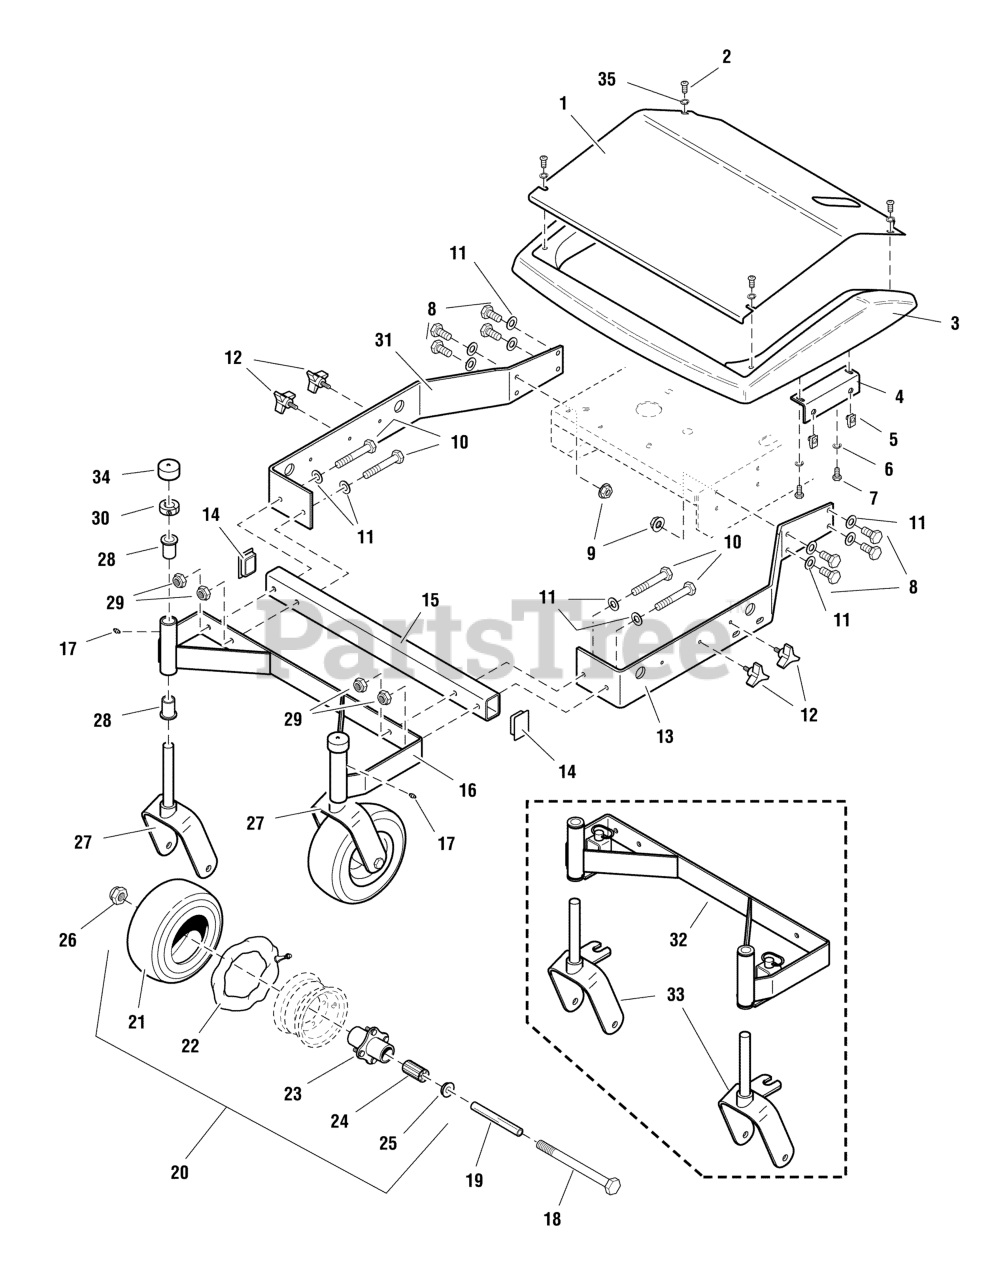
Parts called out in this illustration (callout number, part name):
2	SCREW, Allen Head, 1/4-20 x 1/2
3	GUARD, MOWER HOUSING
4	SHIELD MOUNT BRACKET
5	BODY CLIP, 5/16-18-7GA MATERIAL
6	WASHER, 1/4 LOCK
7	HHCS, 1/4-20 X 0.625, GR5, ZINC/CLEAR
8	BOLT, 3/8-16 X 1" GD5 CZ
9	NUT, 3/8-16 Hex Serrated Flange
10	BOLT, 3/8-16 X 2-1/2" GD5 CZ
11	WASHER, 3/8 SAE
13	FRAME RAIL - LH
14	CAP, Plastic
15	CROSS TUBE
16	ASSM, CASTER MOUNT
17	GREASE FITTING
18	BOLT, 1/2-13 x 5-1/2
19	AXLE, Caster Wheel
20	TIRE ASSM, 9 X 3.5 X 4, SILVER
21	TIRE, Front, 9 x 3.5 x 4
23	HUB & BEARING ASSEMBLY, Complete, Silver
24	BEARING, ROLLER 3/4" ID X 3.25" (ONE PER TIRE)(SV)
25	RETAINER, Bearing
26	NUT, 1/2-13 HEX NYLON LOCK
27	CASTER YOKE
28	BUSHING, Flange
29	NUT, 3/8-16 Hex Nylon Flange
30	COLLAR, 3/4" Split
31	FRAME RAIL - RH
32	CASTER MOUNT FRAME W/ LOCKS, Complete
33	CASTER YOKE
34	CAP,VINYL, 1.375 X 1
35	WASHER, 1/4 SAE
